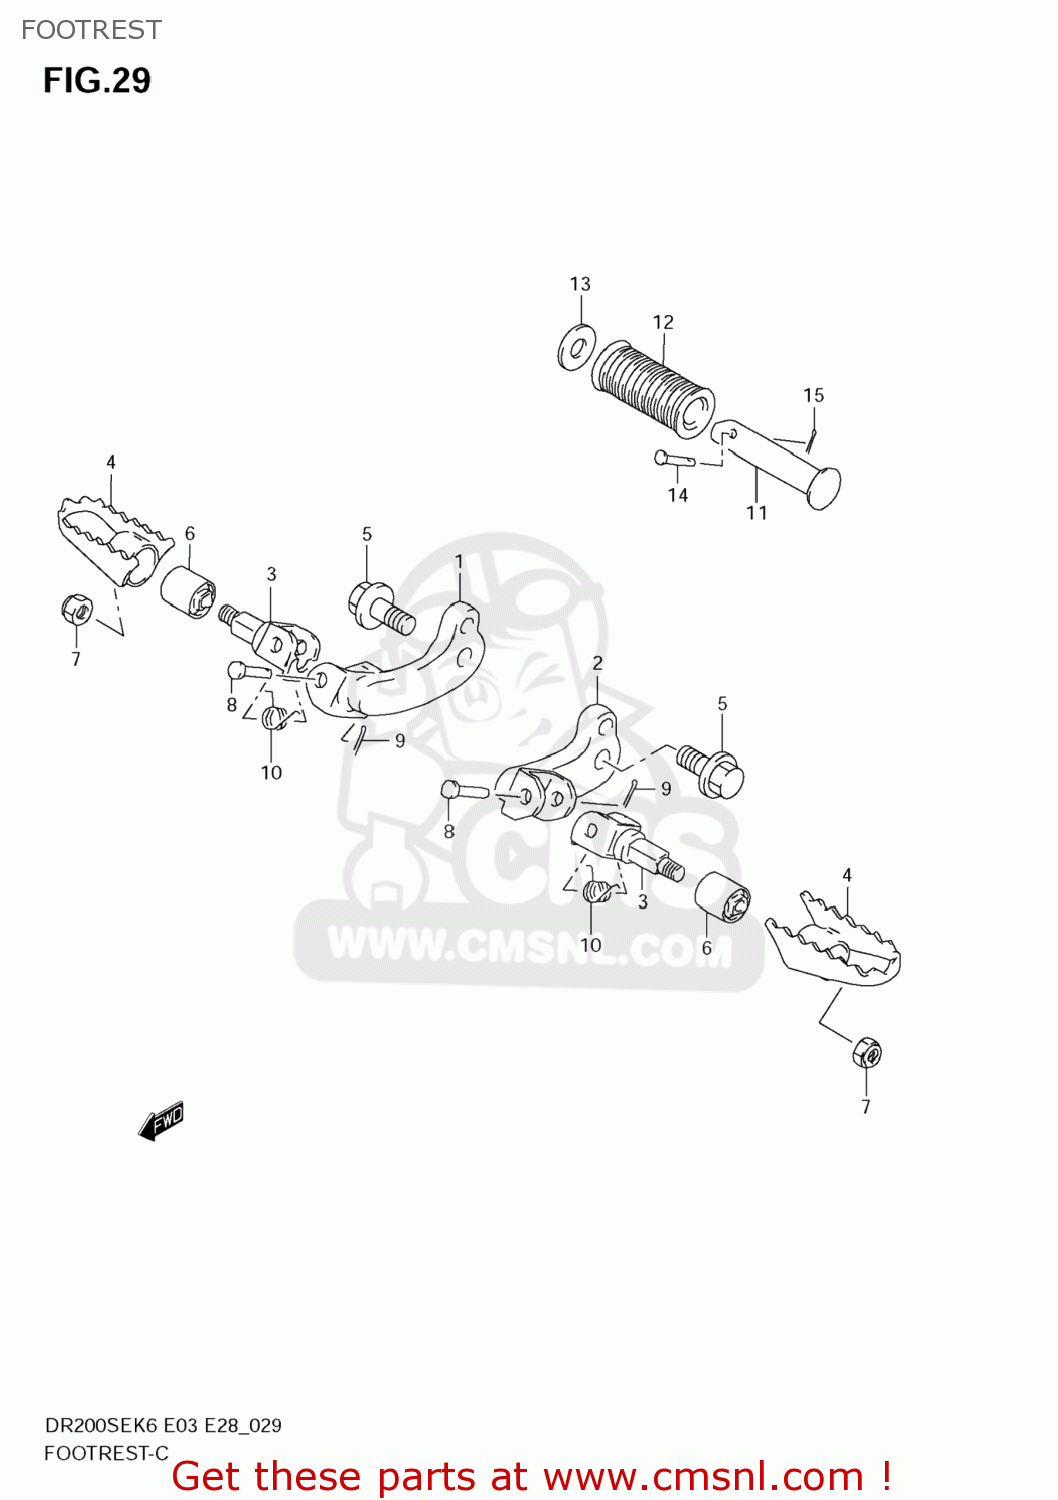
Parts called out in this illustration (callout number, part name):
1	BAR,FR FOOTREST,R
2	BAR,FR FOOTREST,L
3	BRACKET,FR FOOTREST
4	FOOTREST,FR
5	BOLT(12X25)
6	BUSH
7	NUT
8	PIN
9	PIN
10	SPRING
11	BAR,FOOTREST RUBBER
12	RUBBER,PILLION FOOTREST
13	WASHER(19.5X32X2)
14	PIN
15	PIN
